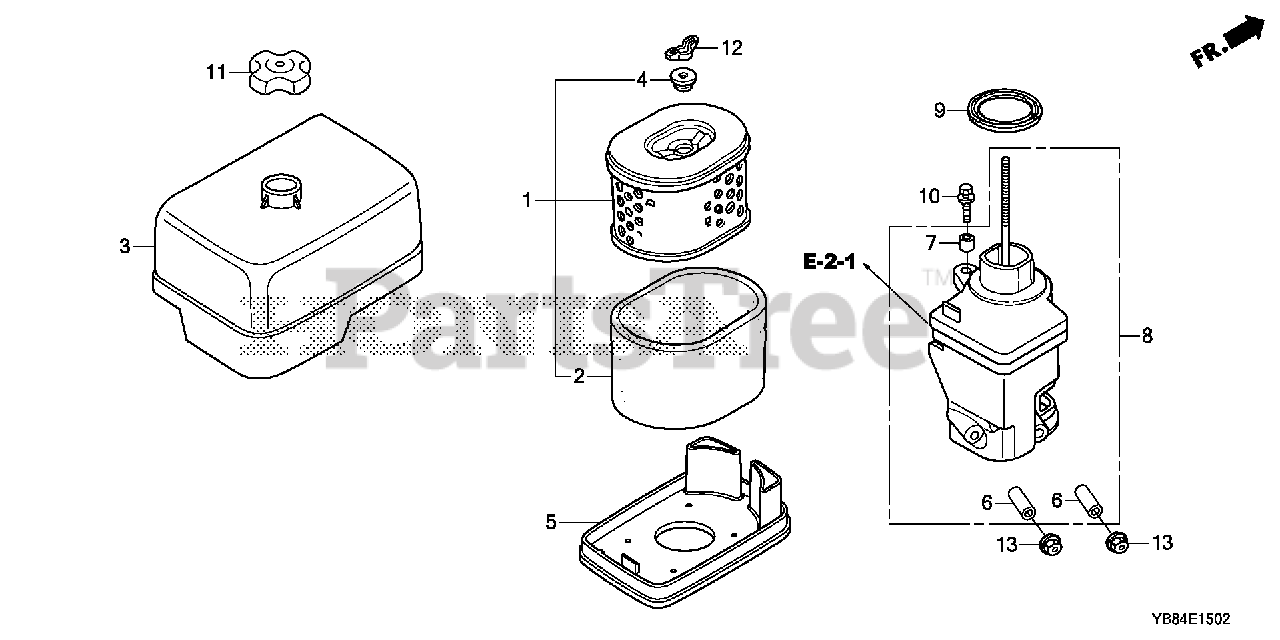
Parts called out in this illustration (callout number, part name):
1	ELEMENT, AIR CLEANER (DUAL)
2	FILTER (OUTER)
3	COVER, AIR CLEANER HOUSING
4	GROMMET, AIR CLEANER
5	NOSE, MUFFLER
6	COLLAR, AIR CLEANER
7	COLLAR B, AIR CLEANER
8	ELBOW, AIR CLEANER
9	GASKET, AIR CLEANER HOUSING
10	BOLT-WASHER (6X22)
11	NUT, AIR CLEANER COVER
12	WINGNUT, TOOL BOX SETTING
13	NUT, FLANGE (6MM)
